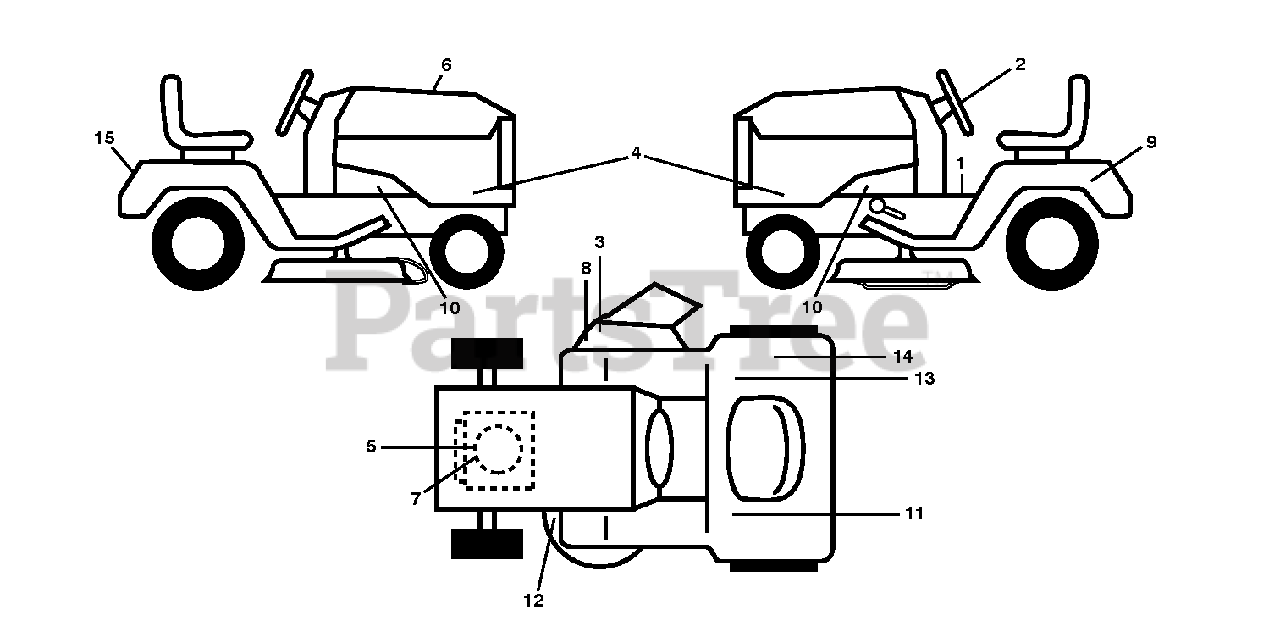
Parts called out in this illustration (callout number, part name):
3	DECAL.INTERNATIONL.CUTFINGER
8	DECAL, DEFLECT WARNING
9	DECAL BTRY SYMBOLS
12	DECAL V BELT SCHEMATIC
13	DECAL PARK BRAKE
